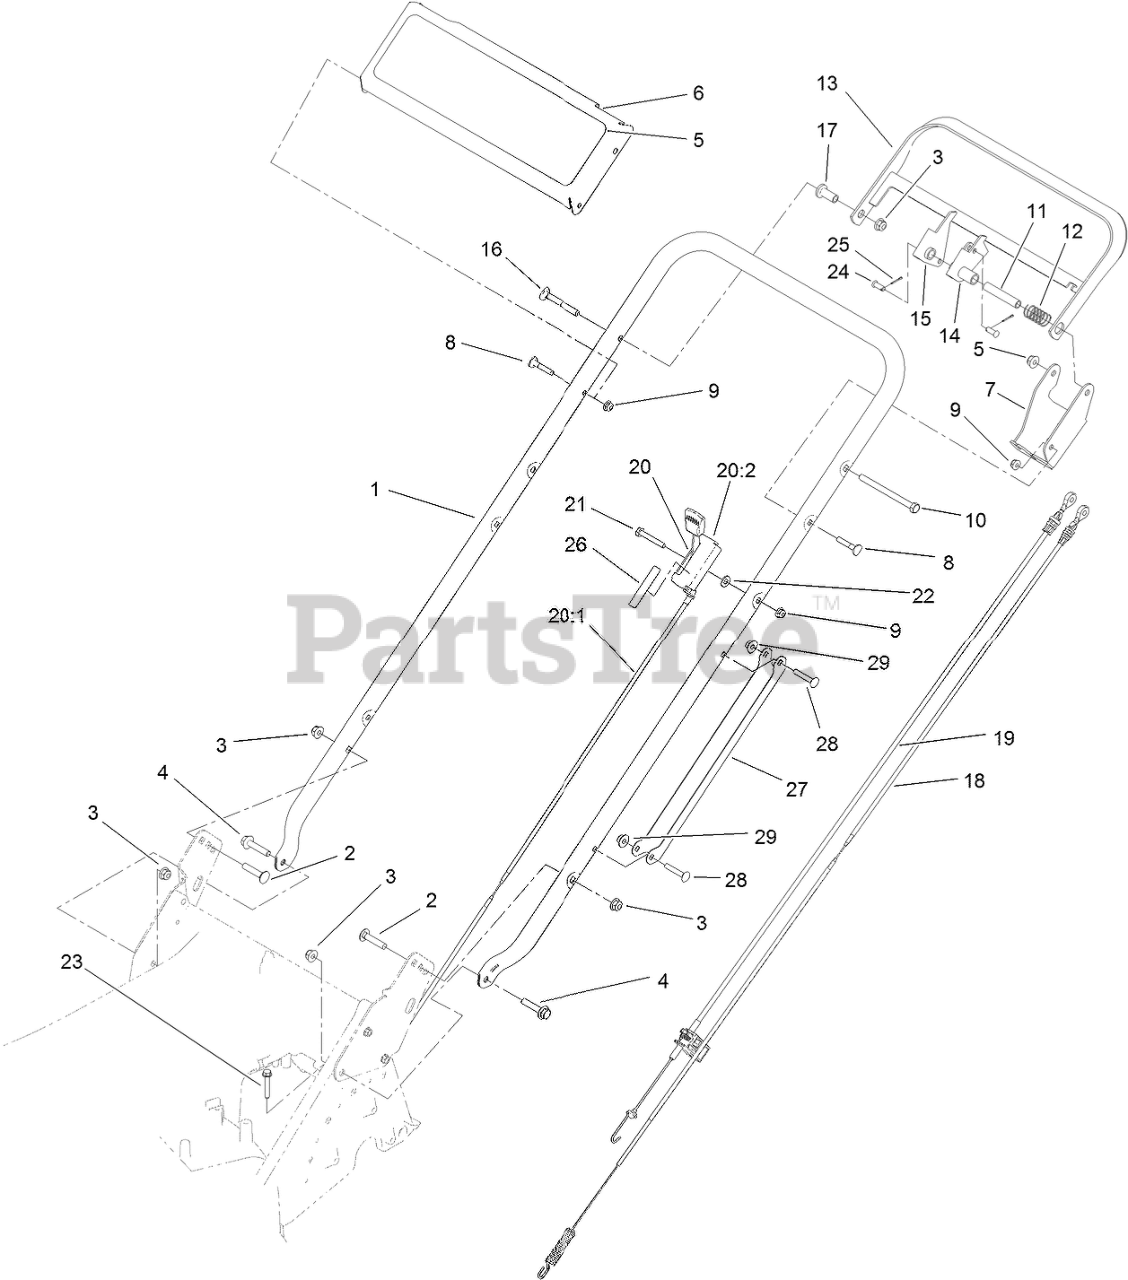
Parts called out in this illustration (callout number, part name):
1	HANDLE
2	BOLT-CARR
3	NUT-HF, NI
4	SCREW-HHF
5	DECAL-TORO, COMMERCIAL
6	PANEL-CONTROL
7	BRACKET-CONTROL
8	SCREW-HANDLE
9	NUT-HF
10	SCREW-HH
11	SPACER
12	SPRING-CONTROL
13	BAR-CONTROL
14	LEVER-CONTROL
15	LEVER-TRACTION
16	SCREW-HANDLE
17	SPACER-FLANGE
18	CABLE-BBC
19	CABLE-TRACTION
20	CONTROL-THROTTLE/CHOKE
20:1	CABLE-THROTTLE
20:2	CONTROL-THROTTLE
21	SCREW-HH
22	WASHER-FLAT
23	SCREW-HWH
24	PIN-CABLE
25	PIN-COTTER
26	DECAL-THROTTLE, CHOKE
27	GUARD-CABLE, HANDLE
28	SCREW-CARR
29	NUT-HEX FLG
